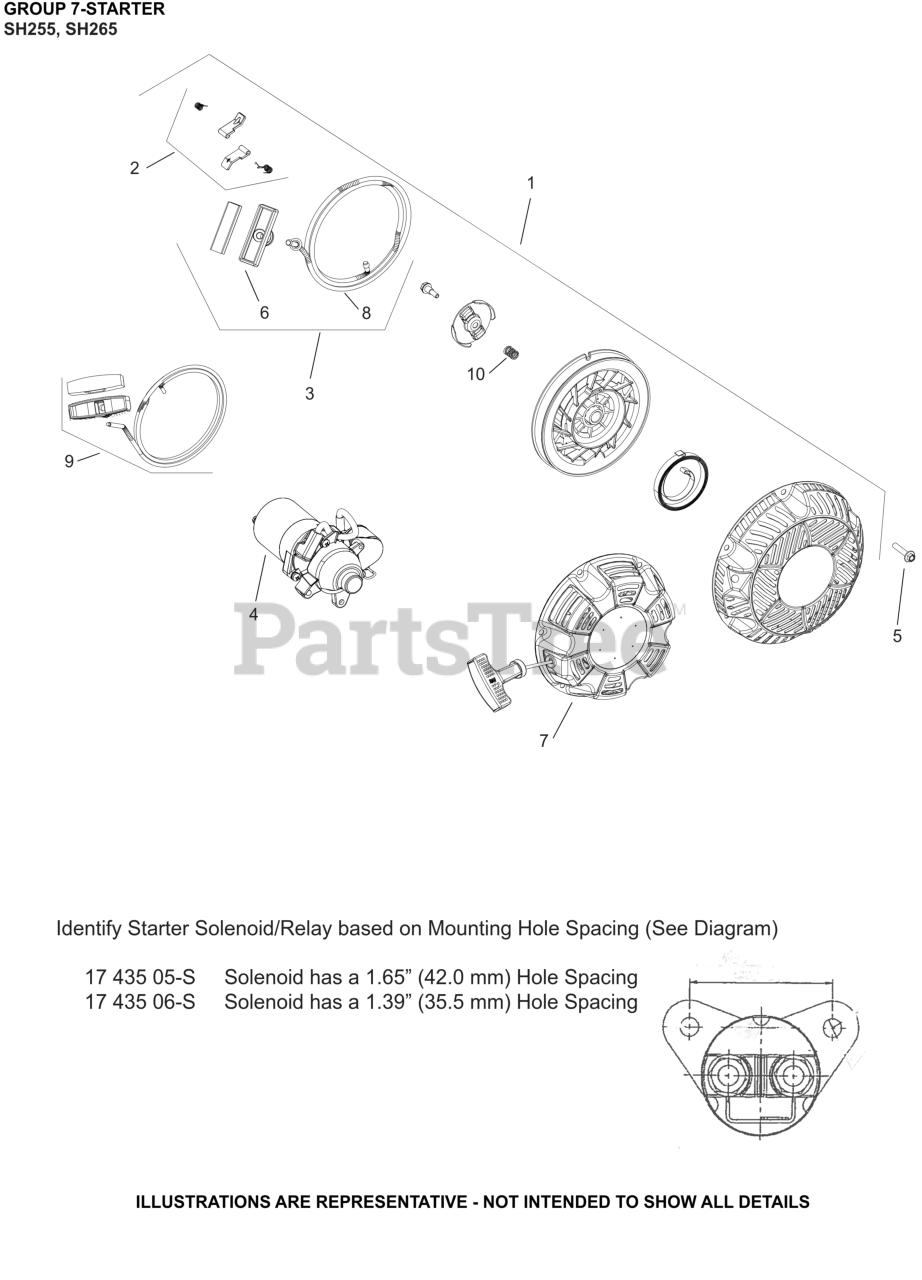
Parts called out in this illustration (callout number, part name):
3	KIT, STARTER ROPE W/HANDLE
7	RETRACTABLE STARTER ASSEMBLY
8	ROPE, STARTING
